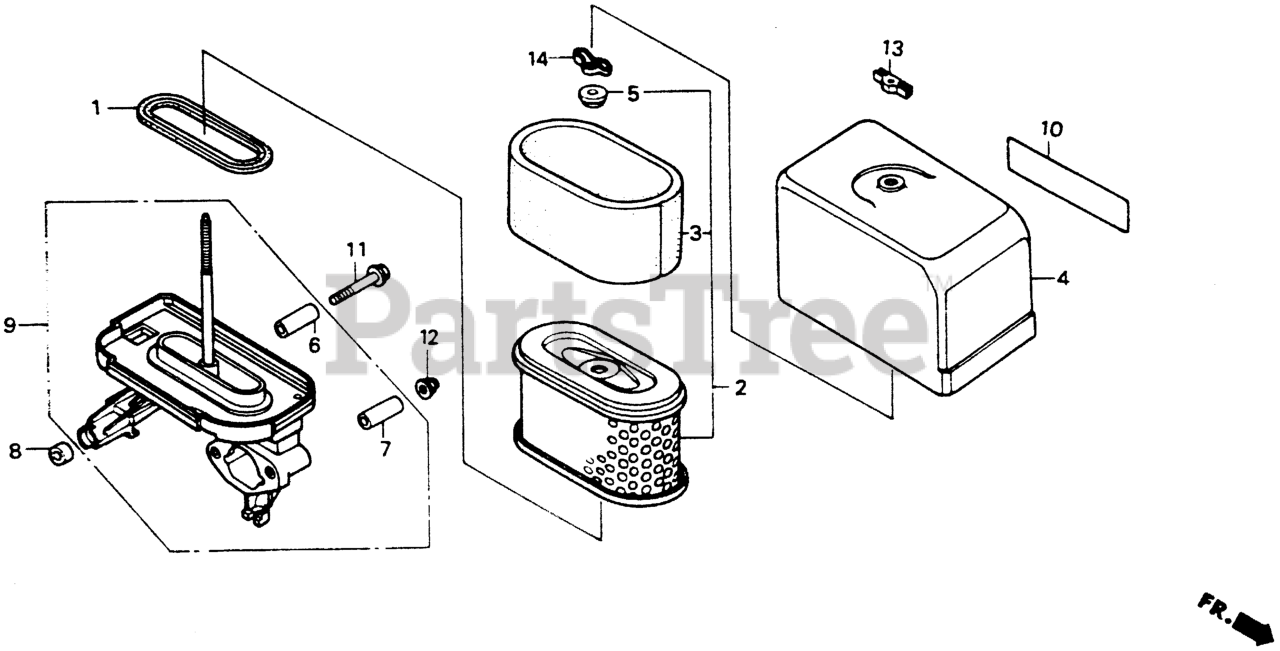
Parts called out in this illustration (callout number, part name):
1	GASKET, ELBOW
2	ELEMENT, AIR CLEANER (METAL BASE)
3	FILTER,OUTER
3	FILTER (OUTER)
4	COVER, AIR CLEANER (DUAL)
5	GROMMET, AIR CLEANER
6	COLLAR, AIR CLEANER Use up to Engine SN 1786084.
7	COLLAR, AIR CLEANER
8	SPACER, AIR CLEANER ELBOW
9	ELBOW, AIR CLEANER
10	MARK, AIR CLEANER CAUTION
11	BOLT, FLANGE (6X45)
12	NUT, CAP (6MM)
13	WINGNUT (6MM)
13	WINGNUT
14	WINGNUT, TOOL BOX SETTING
